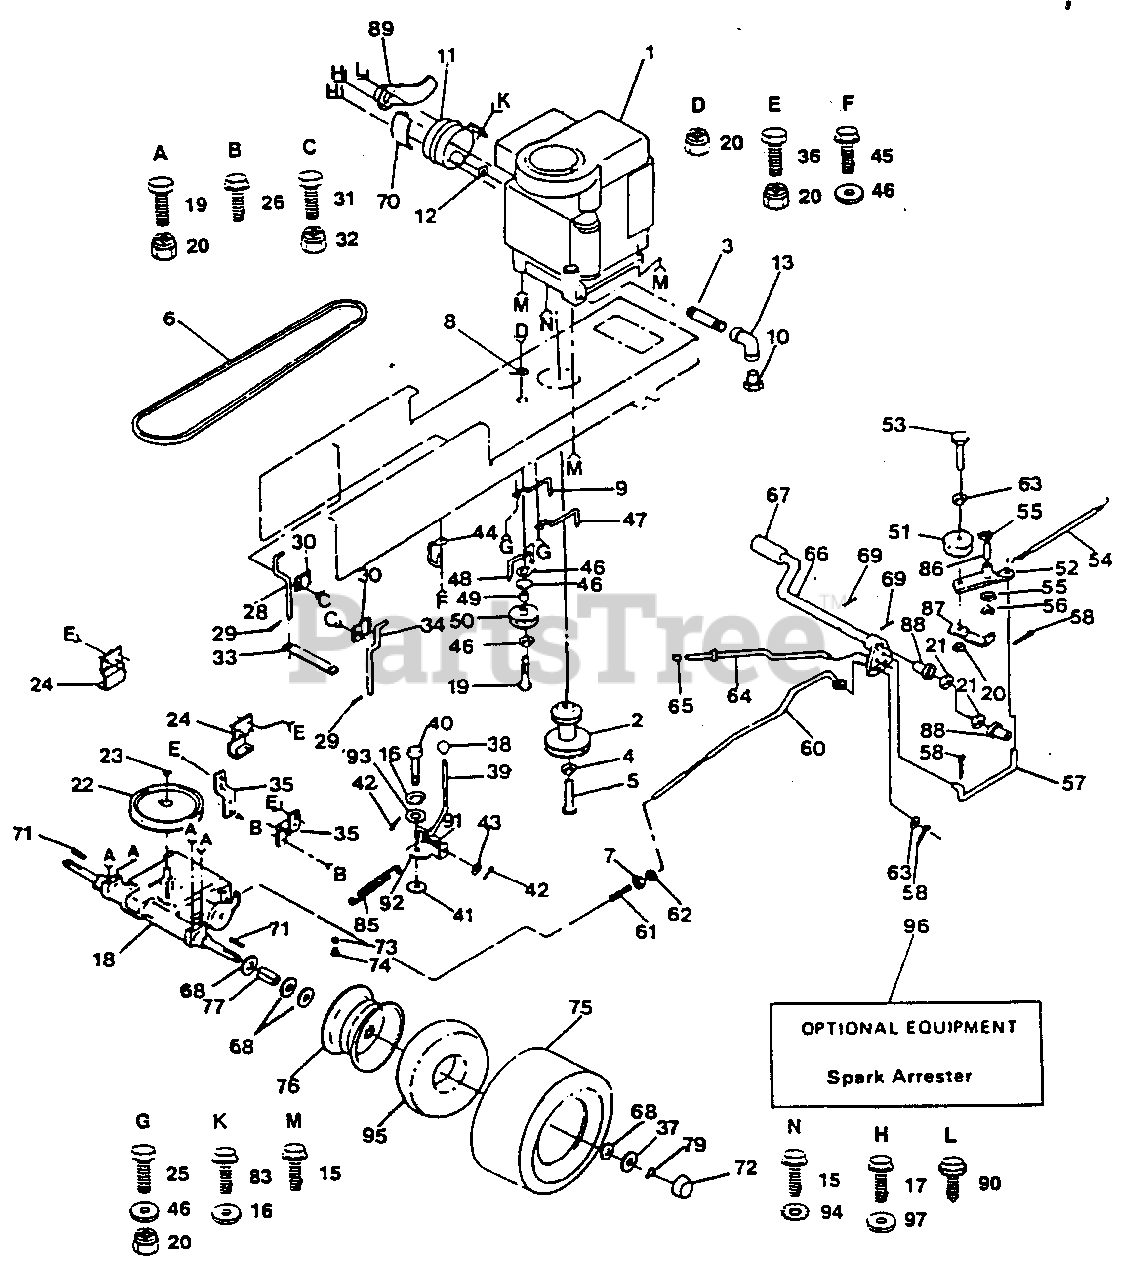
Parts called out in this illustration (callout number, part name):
1	Engine 12 HP, Briggs & Stratton Model No. 281707, Type No. 0412-01 (AYP part number)
2	Pulley, Engine (AYP part number)
3	Nipple, Pipe
4	Washer, Lock 7/16
5	Bolt, Hex 7/16-20 x 1-1/4 (AYP part number)
6	V-Belt, Drive
7	Locknut, Hex 3/8-16 UNC ZN
8	Clip, Fuel Line (AYP part number)
9	Keeper, Belt, Engine
11	Muffler (AYP part number)
12	Gasket (AYP part number)
13	Elbow
15	Screw, Hex, Washer Thread Rolling 3/8-16 x 1-1/4
16	Washer, Lock 1/4
17	Bolt, Hex. Fin 5/16 - 18 UNC x 3-3/8
18	Transaxle Foote, 6 Speed, Model No. 4360-7 (AYP part number)
19	Bolt, Hex 3/8-16 x 2-3/4
20	Nut, Crownlock 3/8-16
21	Washer 21/32 x 1 x 16 Ga
22	Pulley, Transaxle
23	Ring, Retainer (AYP part number)
24	Bracket, Transaxle
25	Bolt, Hex 3/8-16 x 1
26	Screw, Hex Washer Thread Rolling 5/16-18 x 3/4
28	Keeper, Belt, L.H.
29	Retainer, Spring
31	Bolt, Hex 5/16-18 x 3/4
32	Nut, Crownlock 5/16-18 x 3/4
33	Strap, Locator
34	Keeper, Belt, R.H.
35	Strap, Torque, Transaxle
36	Bolt, Hex 3/8-16 x 3/4 (AYP part number)
37	Washer, 25132 x 1-5/8 x 16 Ga.
38	Knob, Shift
39	Rod, Shift
40	Bolt, Shift Plate (AYP part number)
41	Washer, Shift Plate
42	Pin, Cotter 1/8 x 1
43	Washer 15/32 x 3/4 x 16 Ga.
44	Belt, Retainer (AYP part number)
45	Screw, Hex, Washer Thread Rolling 3/8-16 x 3/4
46	Washer 13/32 x 13/16 x 12 Ga.
47	Keeper, Belt, Engine
48	Retainer, Belt
49	Spacer
50	Idler, Flat
51	Pulley, Idler (AYP part number)
52	Arm, Idler
53	Bolt, Hex 3/8-16 x 1-1/2 (AYP part number)
54	Spring, Return Clutch
55	Washer, Hardened
56	Ring, Klip
57	Link, Clutch
58	Pin, Cotter 1/8 x 3/4
60	Rod, Brake
61	Spring, Rod, Brake
62	Nut, Jam 3/8-16
63	Washer 13/32 x 13/16 x 16 Ga.
64	Rod, Brake, Parking (AYP part number)
65	Cap, Plunger
66	Shaft, Foot Pedal (AYP part number)
67	Cover, Pedal (AYP part number)
68	Washer 25/32 x 1-1/4 x 16
69	Pin, Roll 3/16 x 1 (AYP part number)
70	Shield, Heat, Muffler
71	Key, Square 3/16 x 2
72	Cap, Axle (AYP part number)
73	Cap, Valve
74	Stem, Valve
75	Tire, Rear
76	Rim Assembly, Rear (AYP part number)
77	Spacer
79	E-Ring
83	Bolt, Fin Hex 1/4-20 UNC x 1/2
85	Spring, Brake (AYP part number)
86	Bearing
87	Retainer, Belt
88	Bearing, Nylon
89	Deflector, Asm., Muffler
90	Screw, Spiderlock, Hex HD #8 x 1/2 AB (AYP part number)
92	Plate, Shift
93	Washer 9/32 x 3/4 x 10 Ga.
94	Washer, Lock, External Tooth 3/8
95	Tube, Tire (not furnished with tractor)
96	Spark Arrester (AYP part number)
97	Washer, 11/32 x 5/8 x 12 Ga.
